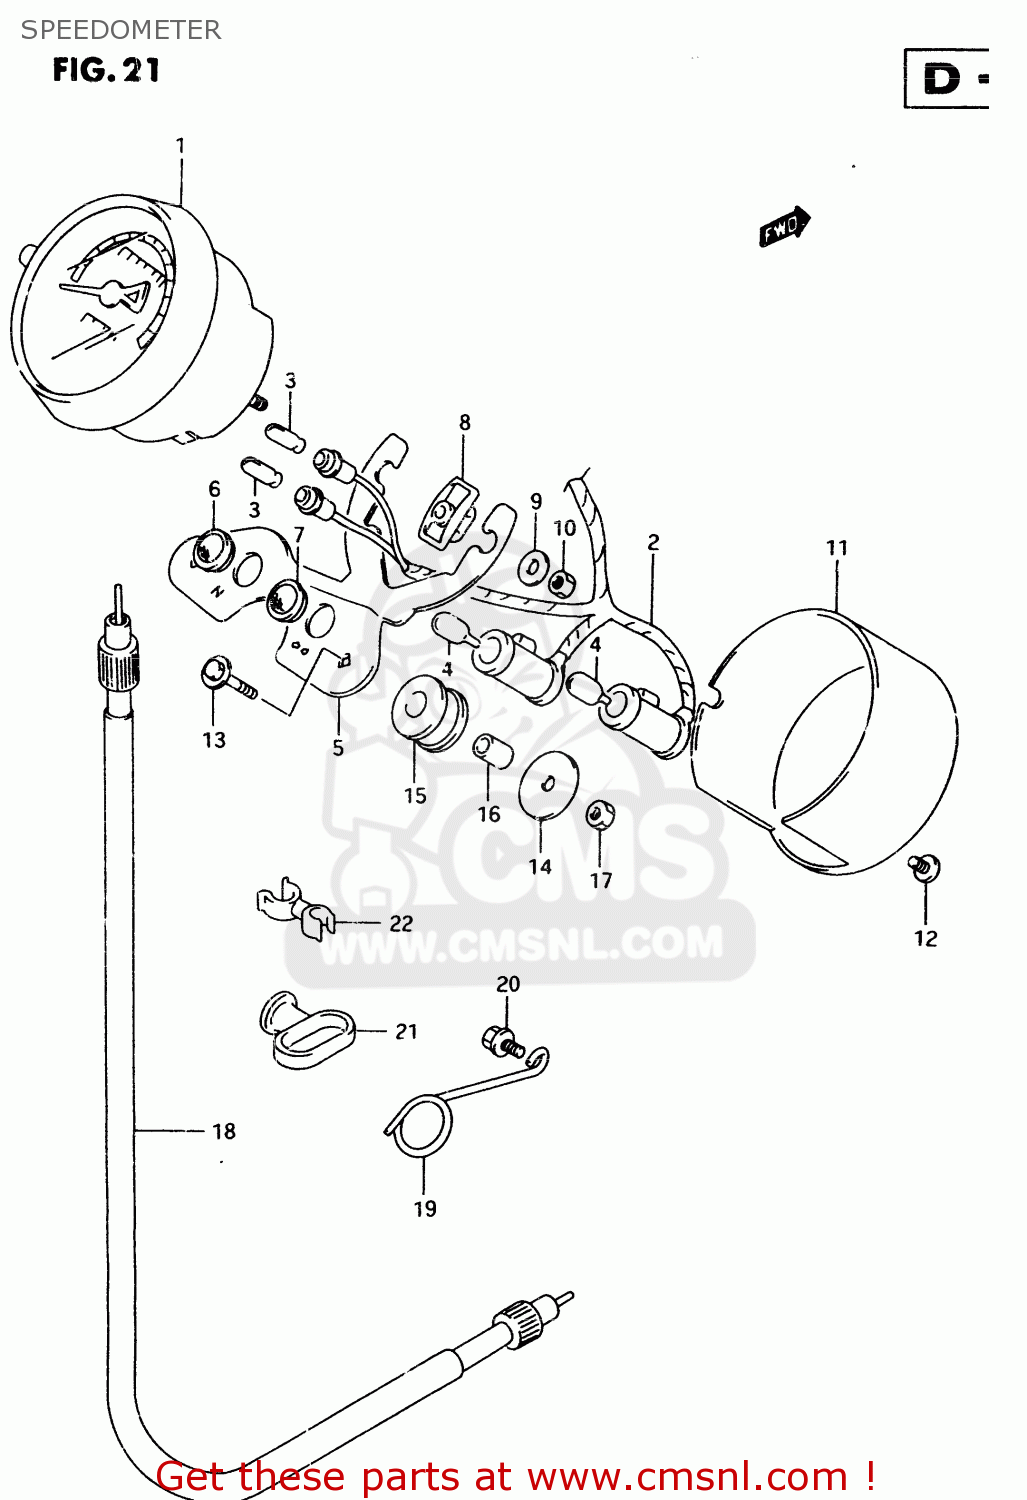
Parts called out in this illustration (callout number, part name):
1	SPEEDOMETER
2	SOCKET ASSY
3	BULB(12V1.7W,T6.5)
4	BULB(12V3.4W,T10)
5	BRACKET,METER
6	LENS(GREEN)
7	LENS,TURNSIGNAL(ORANGE)
8	CUSHION,DAMPER
9	WASHER(5.2X16X1)
10	NUT
11	COVER,UNDER(CHROMUN)
12	SCREW
13	BOLT(6X30)
14	WASHER (6.5X29X1.6)
15	CUSHION,METER BRACKET
16	SPACER(6.5X10X15.7)
17	NUT 6MM
18	CABLE ASSY,SPEEDOMETER
19	GUIDE,SPEEDOMETER CABLE
20	BOLT
21	GUIDE,CABLE
22	CLIP
